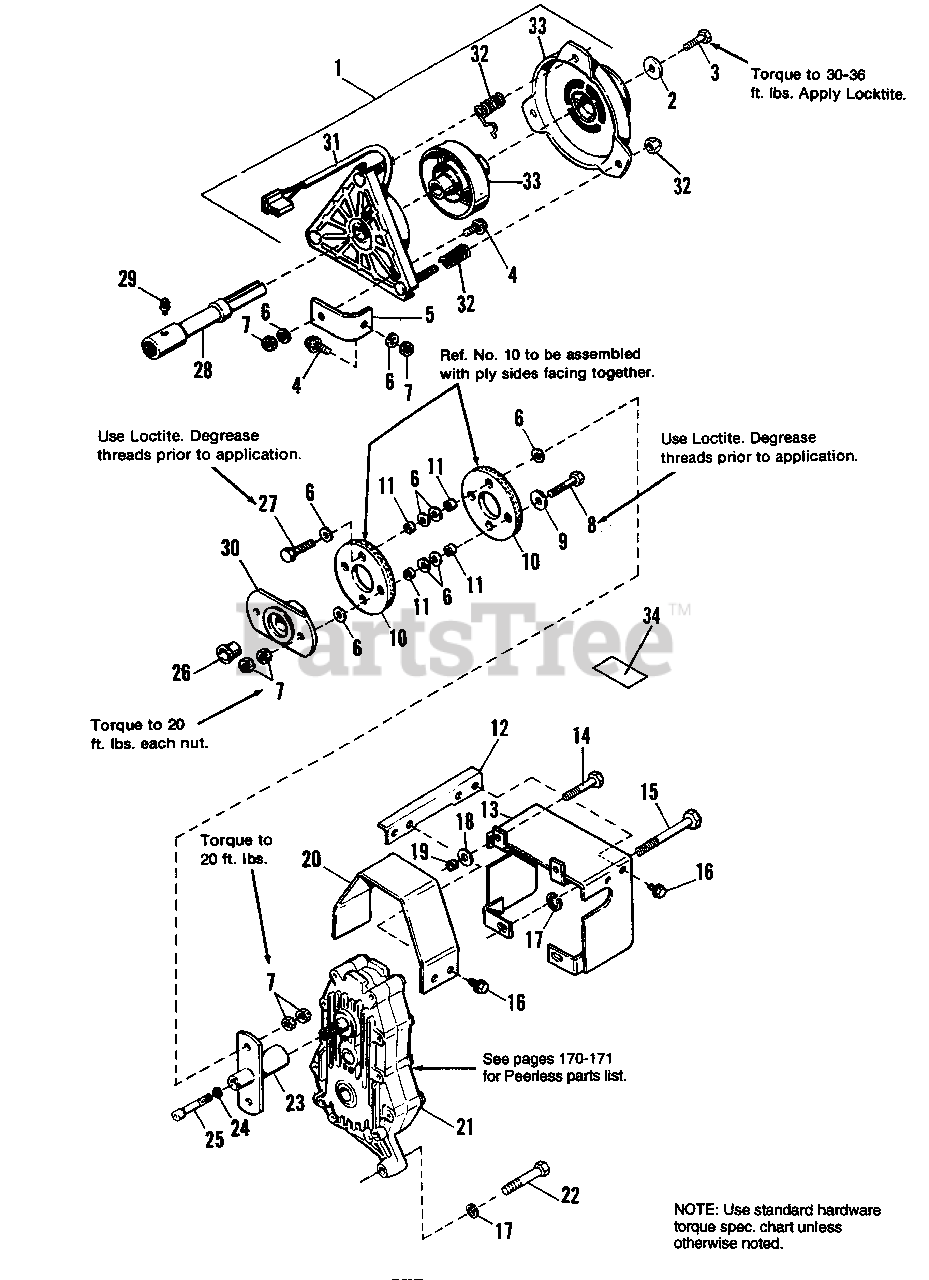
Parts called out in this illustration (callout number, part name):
1	CLUTCH, Electric
3	CAPSCREW, Hex Hd., 3/8-16 x 1, Gr. 5
4	CAPSCREW, Whizlock, 5/16-18 x 3/4, Gr. 5
5	TORQUE STRAP KIT
6	WASHER, Plain, 5/16
7	NUT, Hex, Centerlock, 5/16-18
8	CAPSCREW, Hex Head 5/16-18 x 2 G5
9	WASHER, Plain, 5/16 x 1-1/2 x 9/64
10	COUPLING, Flex
12	SUPPORT, P.T.O. Guard
13	GUARD ASSY., P.T.O.
14	CAPSCREW, Hex Head 5/16-18 x 2 G5
15	CAPSCREW, Hex Hd., 1/2-13 x 4, Gr. 8
16	CAPSCREW, Washer Hd., Taptite, 5/16-18 x 1/2
17	LOCKWASHER, 1/2
18	WASHER, , Plain, 5/16
20	GUARD, Disc.
21	GEAR BOX, 2000 RPM (Peerless)
22	CAPSCREW, Hex Hd., 1/2-13 x 2-1/4, Gr. 8
23	ADAPTER ASSY.
24	LOCKWASHER, 5/16
25	CAPSCREW, Hex Hd, 5/16-24 x 2-1/4
27	CAPSCREW, Hex Hd., 5/16-18 x 1-1/2, Gr. 5
28	SHAFT ASSY.
29	FITTING, Grease w/Ball
31	FIELD ASSY.
32	ACCESSORY KIT
33	ROTOR, ARMATURE & BRAKE ASSY.
34	DECAL, Rear P.T.O.
